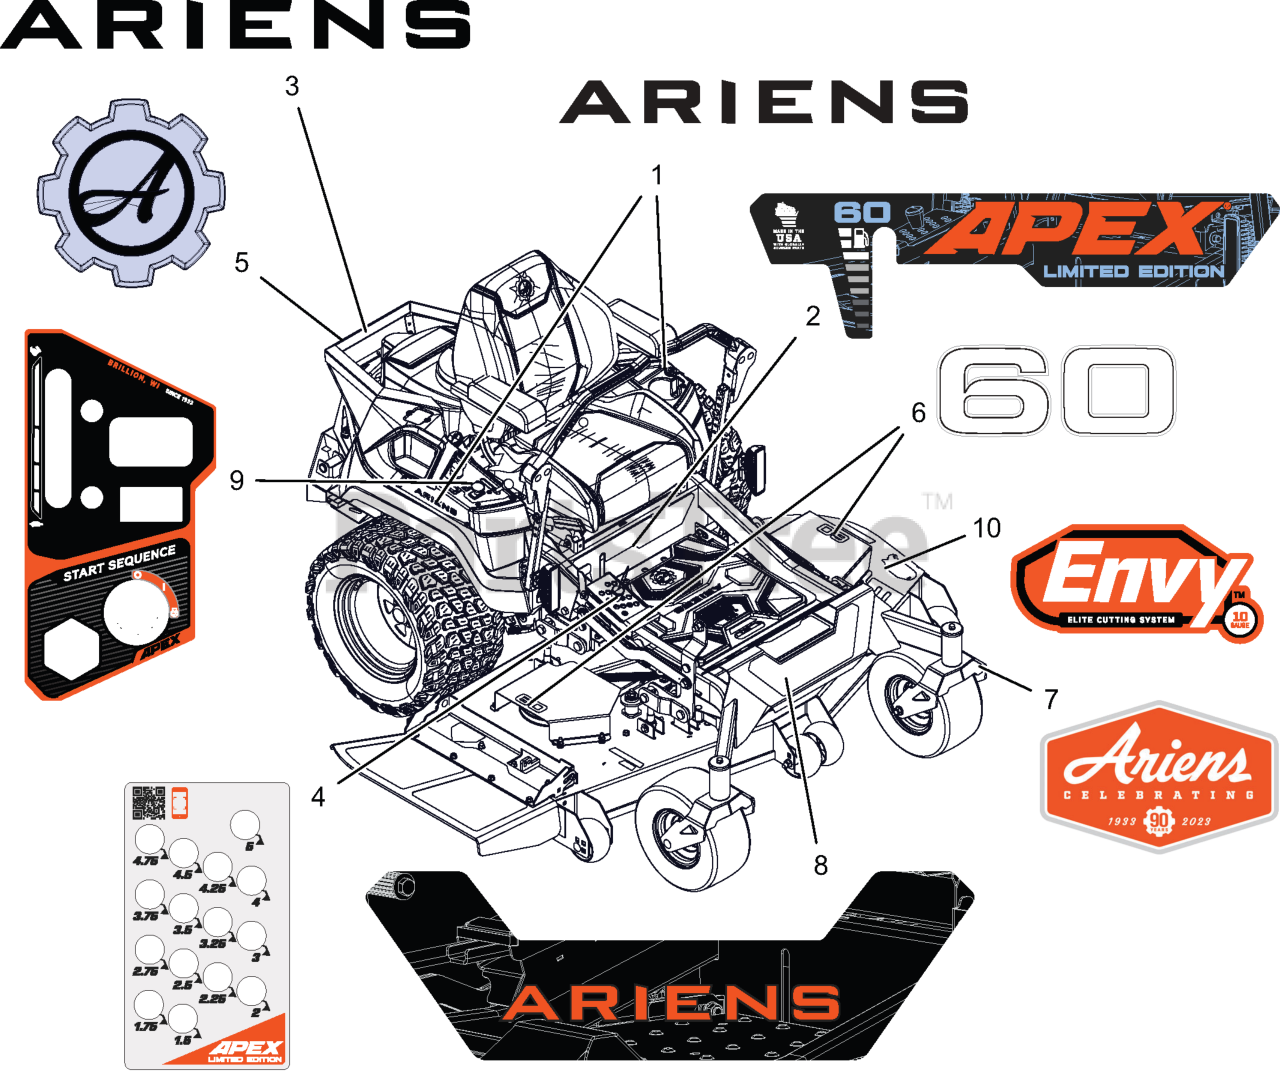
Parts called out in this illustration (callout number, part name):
1	DECAL- ARIENS 6.000" BLACK
2	DECAL- KICKPLATE APEX LE
3	DECAL- ARIENS 9.625" BLACK
4	DECAL- HOC APEX LE
5	DECAL- ARIENS GEAR BADGE
6	DECAL- DECK 60 APEX LE
7	DECAL- 90TH APEX LE
8	DECAL, FOOTREST APEX LE
9	DECAL- DASH -APEX
10	DECAL- DECK -ENVY
